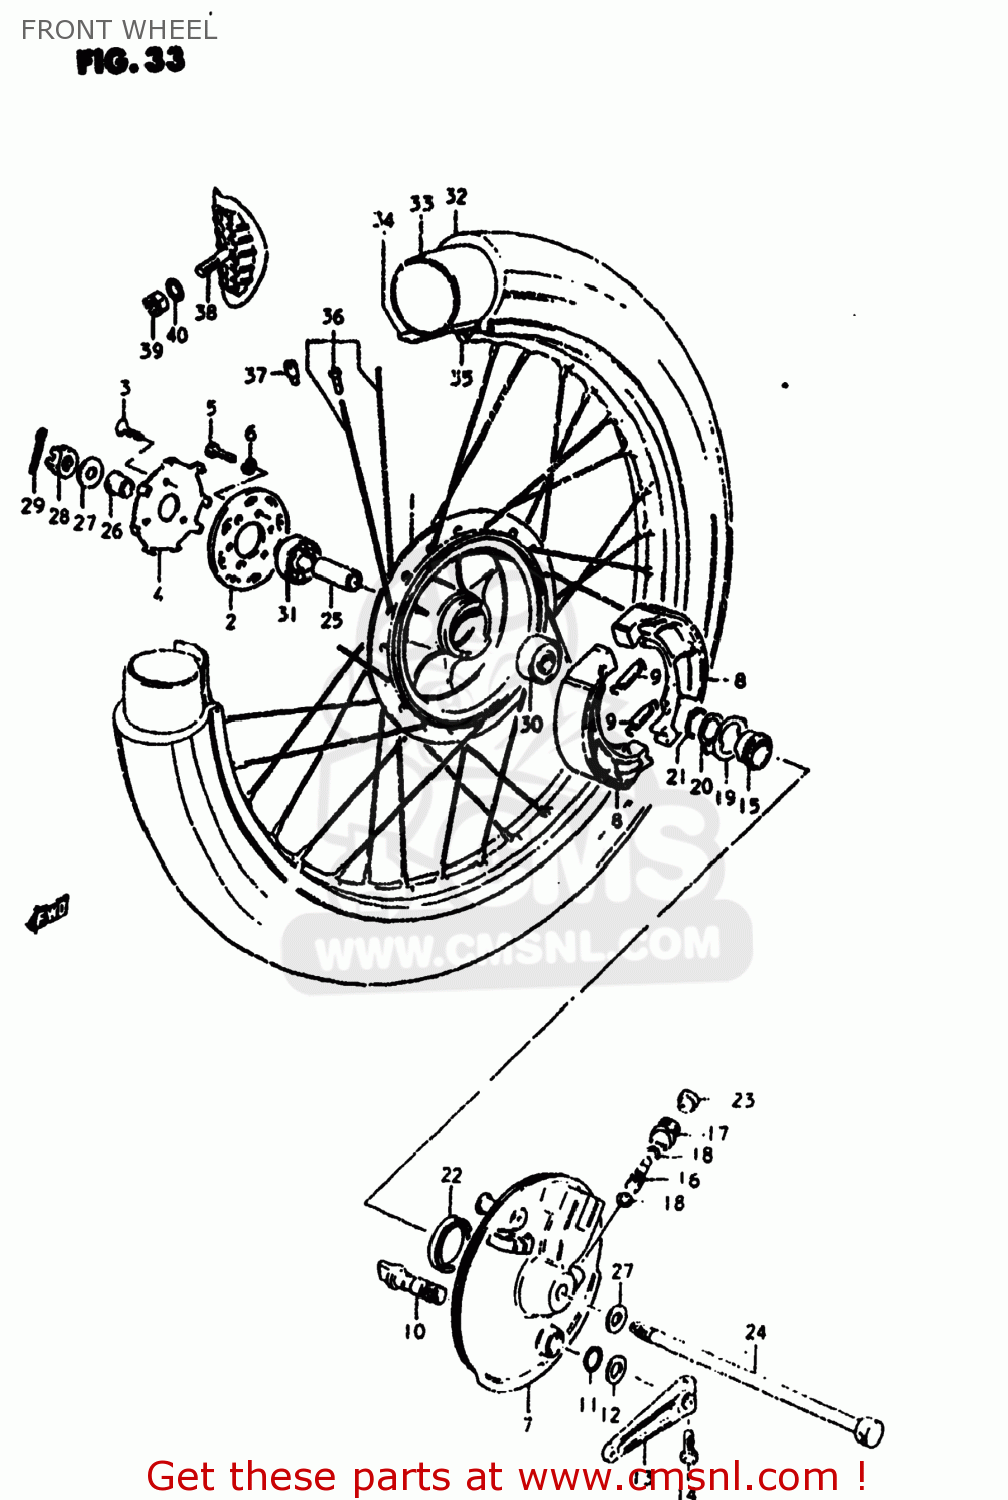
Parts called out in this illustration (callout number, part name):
1	DRUM,FRONT HUB
2	FLANGE,FR HUB,R
3	SCREW
4	RETAINER,FR HUB BEARING,R
5	BOLT, UPPER
6	LOCK WASHER
7	PANEL,FRONT HUB
8	SHOE,BRAKE (MCA)
9	SPRING
10	CAM,FRONT BRAKE
11	O-RING,BOSS
12	WASHER (15X24X1.6)
13	LEVER,FRONT BRAKE CAM
14	BOLT
15	GEAR,SPEEDOMETER
16	PINION,SPEEDOMETER
17	BUSHING,SPEEDOMETER PINION
18	WASHER (5.1X9X0.4)
19	DRIVER,SPEEDOMETER GEAR
20	WASHER(22.5X27X1)
21	CIRCLIP
22	SEAL,OIL(26X38X4)
23	SEAL,OIL(6X10X3)
24	AXLE,REAR
25	SPACER (12.6X19X52)
26	SPACER,FR AXLE,R
27	WASHER
28	NUT, REAR AXLE
29	COTTER PIN
30	BEARING
31	BEARING, RH
32	TIRE,FRONT
33	TUBE
34	PROTECTOR,WHEEL,INNER
35	RIM,FRONT WHEEL
36	SPOKE SET,FR
37	BALANCER,WHEEL (50G)
38	STOPPER,BEAD
39	NUT
40	WASHER
